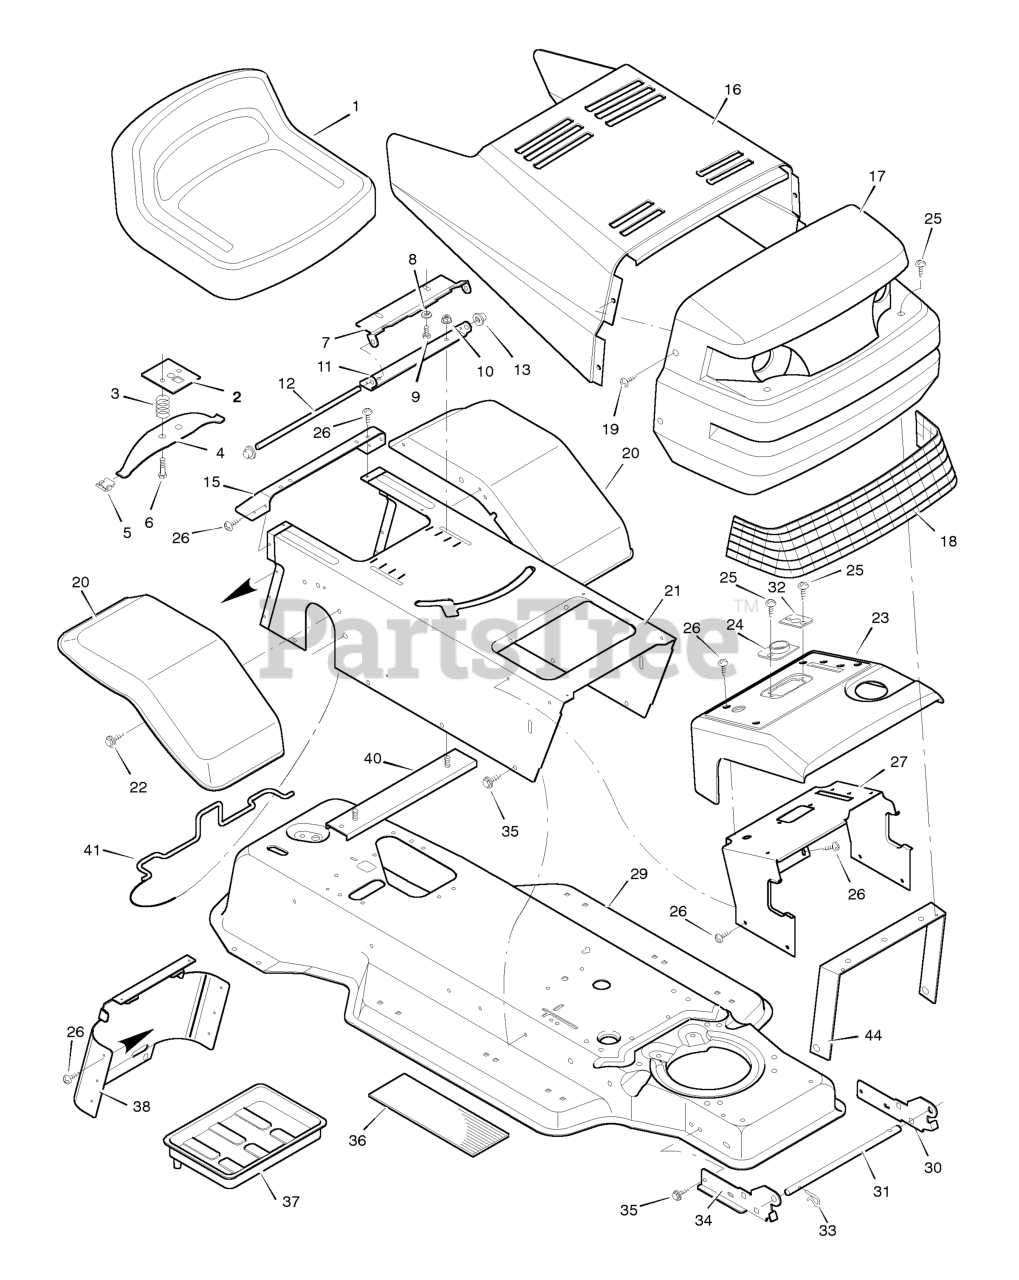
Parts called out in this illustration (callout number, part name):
2	Plate Assembly, Switch
3	Spring, Compression
4	Spring, Seat
5	Glide, Spring
6	Bolt, Shoulder
7	Support, Seat
8	Lockwasher
9	Bolt, Hex
10	Locknut, Flange
11	Bracket, Pivot
12	Rod, Pivot
13	Cap, Push On
15	Fender, Apron
17	Grille Assembly
21	Console Assembly
23	Dash Panel
24	Bearing, Steering
26	Screw
27	Support, Dash
29	Frame Assembly
30	Bracket, Left Grille
31	Rod, Pivot
32	Bearing
33	Pin, Hair
34	Bracket, Right Grille
37	Tray, Battery
38	Cap, Console
39	Bolt
40	Channel Assembly
41	Clamp, Battery
44	Brace, Grille
